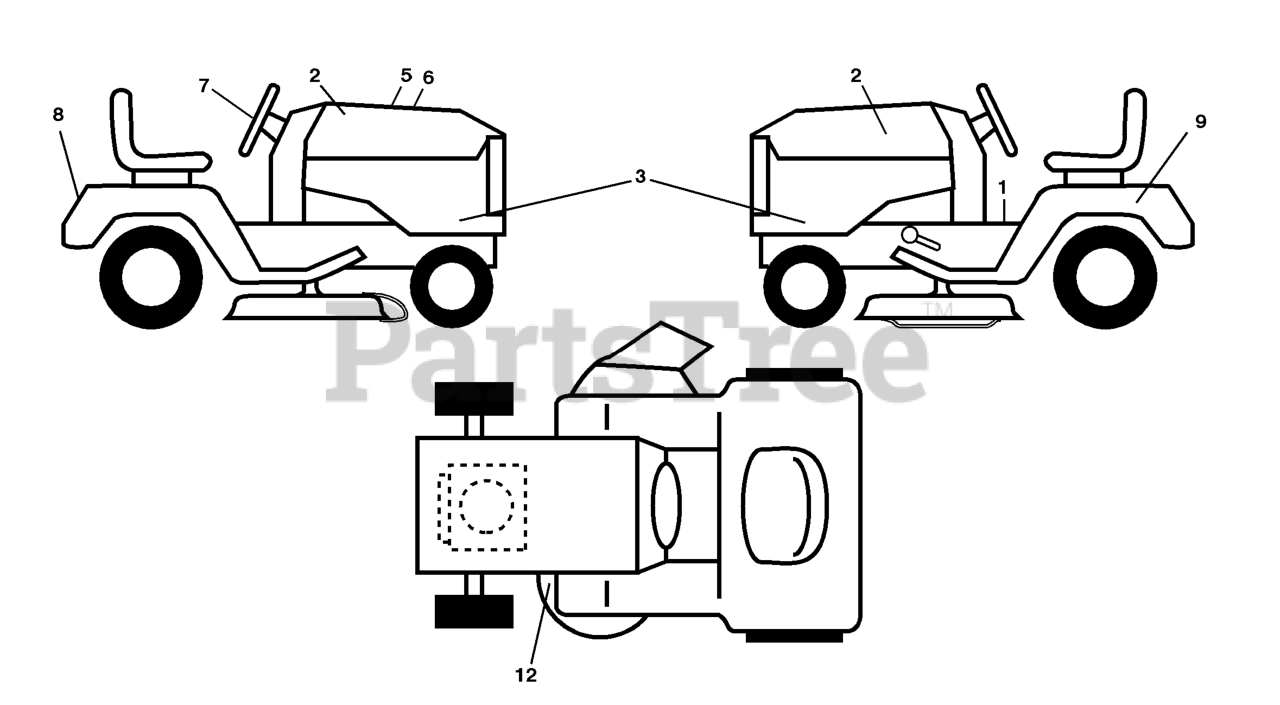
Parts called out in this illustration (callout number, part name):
1	DECAL.WARN.START.INSTRUCTIONS
2	DECAL.HOOD.LOGO.HUSQVARNA
3	DECAL, HOOD PANEL SD
5	DECAL HOOD CUST. RESP.
6	DECAL.RPL.KH.SV600.TLW.46"
7	DECAL.WHEEL.STRG.LGN.H
8	DECAL.FENDER
9	DECAL BTRY SYMBOLS
12	DECAL V BELT SCHEMATIC
12	DECAL.BYPASS.FENDER.CRD.LT.YT
12	PAD, FOOTREST, LH
12	PAD, FOOTREST, RH
12	DECAL.PDL CNTRL.HYD.LOWES.BLUE
12	Manual, Owner's
